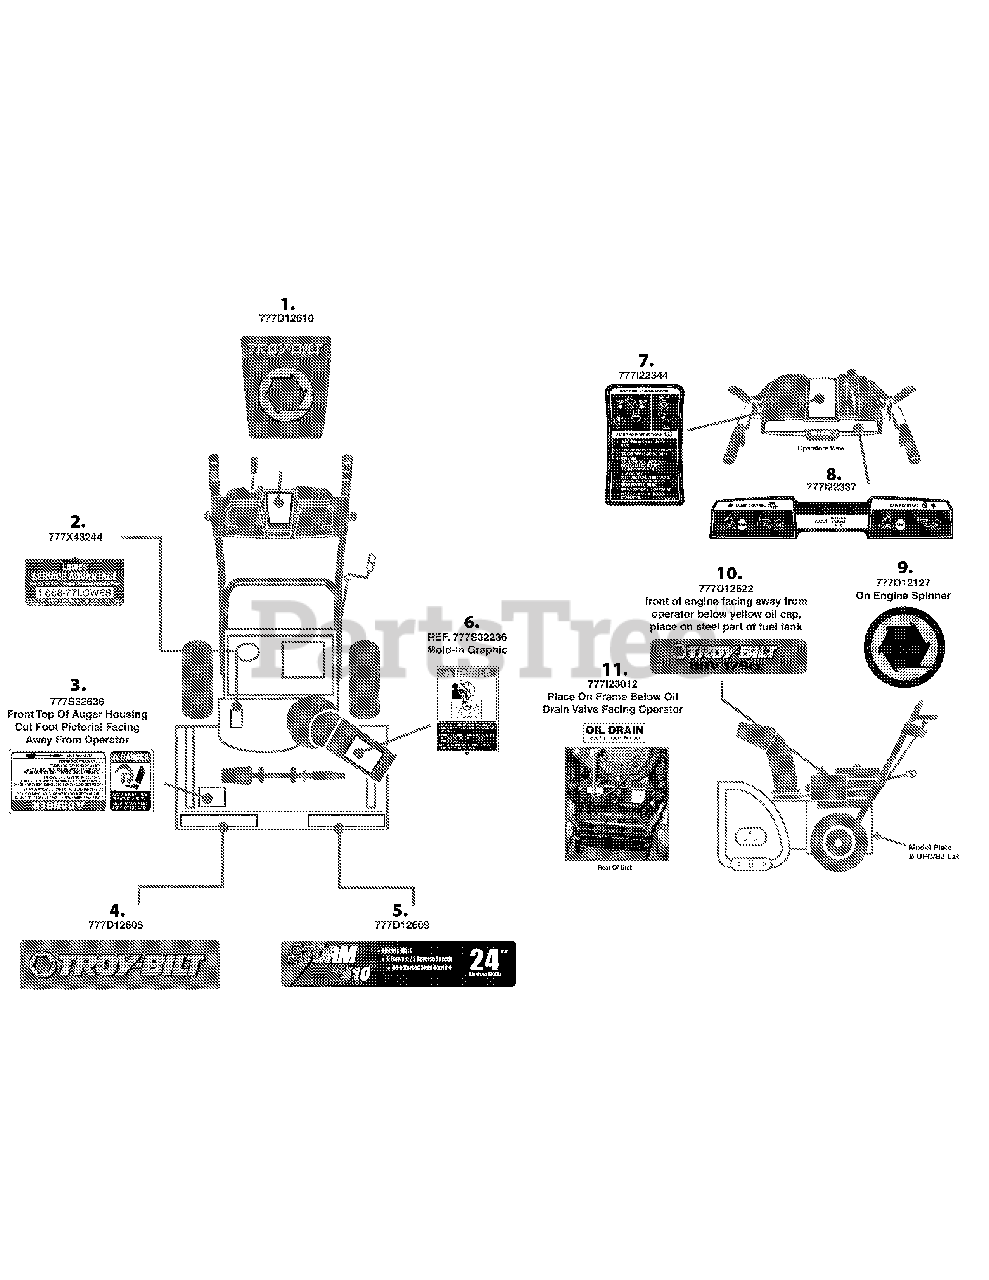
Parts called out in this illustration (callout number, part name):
1	LABEL-SNOW HANDLE N STYLE TROY
2	LABEL-LOWES:SERVICELBL
3	LABEL-SNOW HOUSING
4	LABEL-SNOW FRONT LH AUGER TROY
5	LABEL-SNOW FRONT RH AUGER STORM
6	LABEL-SNOW CHUTE
7	LABEL-CHUTE CONTROL
8	LABEL-HANDLE PNL AUGER/DRIVE CTRL
9	LABEL-TILLER MTD ENGINE
10	LABEL-MTD ENGINE TROY
11	LABEL-SNOW OIL DRAIN
